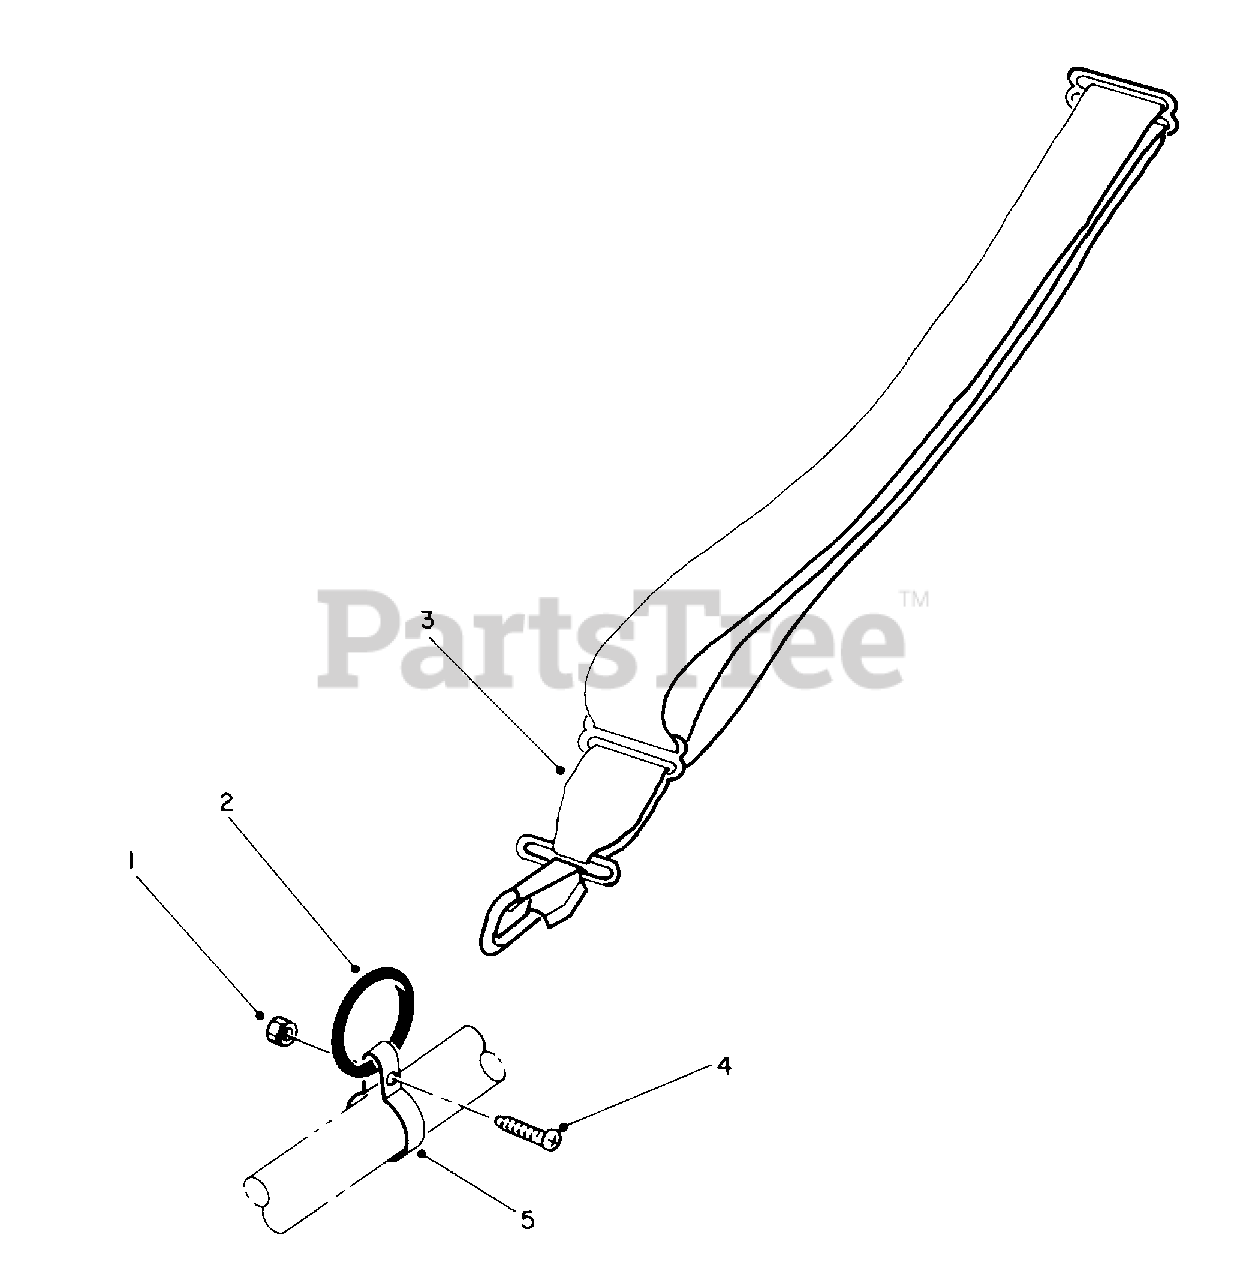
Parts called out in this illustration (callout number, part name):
1	Nut
2	Ring
3	Standard Harness
4	Screw
5	Clamp
